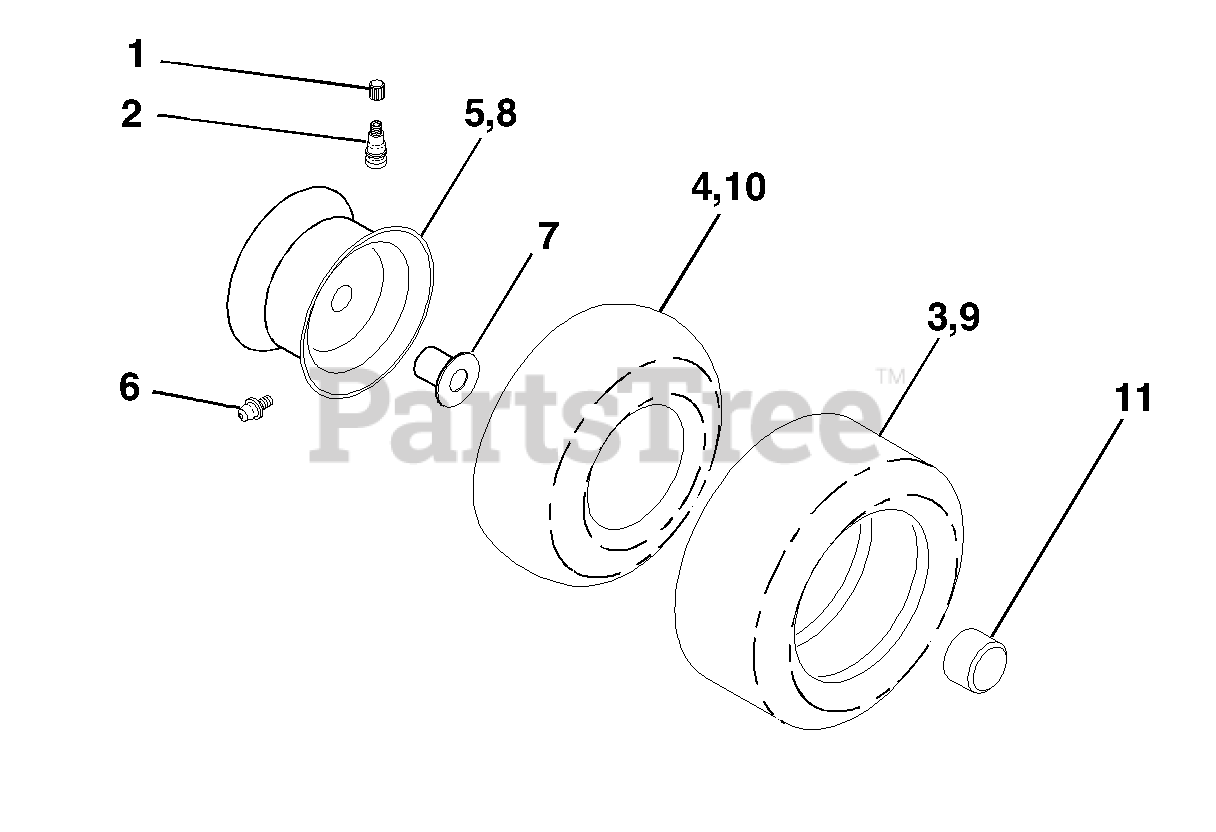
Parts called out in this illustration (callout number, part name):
1	Cap Valve Tire
2	Stem Valve
3	Tire F T 15 X 6 0 - 6 Service
4	Tube Front
5	Rim Asm 6" front Service
6	Fitting Grease
7	Bearing Flange
8	Rim Asm 8"rear Service
9	Tire R T 20x10-8 Service
10	Tube Rear
11	Cap Axle Blk 1 50 X 1 00
